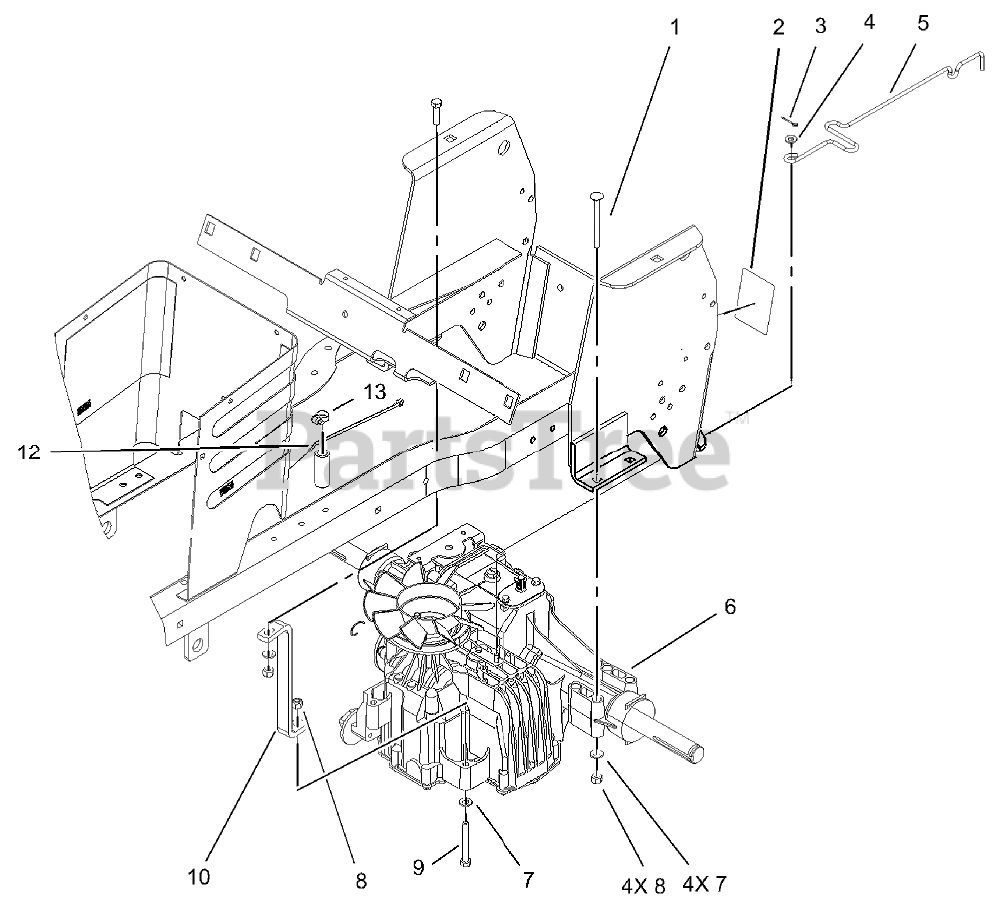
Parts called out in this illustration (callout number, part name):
1	SCREW-CARR
2	DECAL-VALVE, HYDRO
3	PIN-COTTER
4	WASHER-FLAT
5	ROD-BYPASS
6	TRANSAXLE-HYDROSTATIC
7	WASHER-PLAIN
8	NUT-LOCK, NI
9	SCREW-HH
10	Strap-Torque
12	TIE-CABLE
13	CLAMP-HOSE, WORM DRIVE
